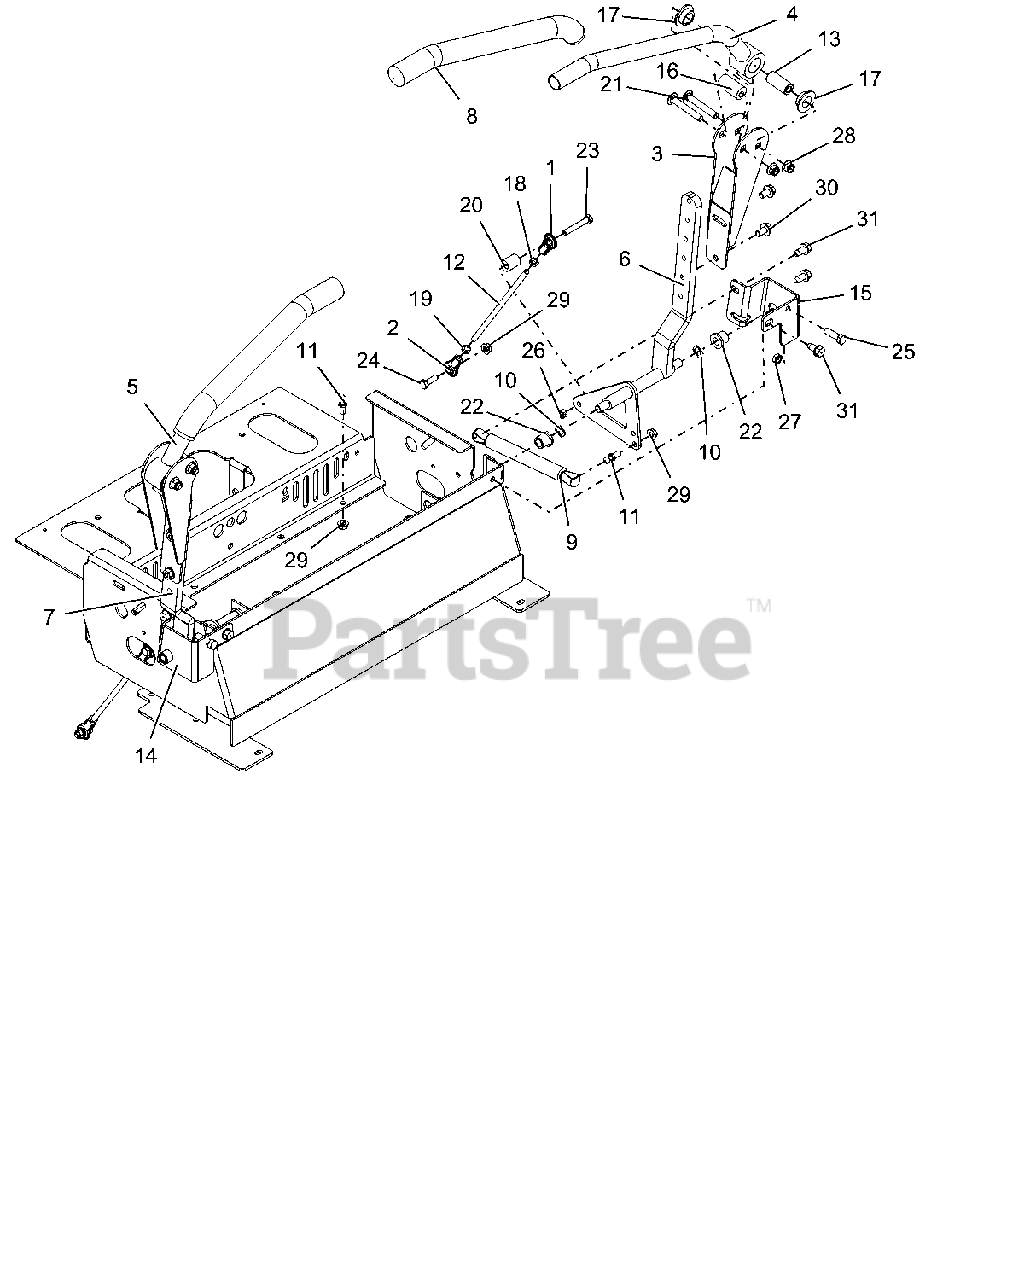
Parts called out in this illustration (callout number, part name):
1	ALIGNABALL, 5/16 RH THREAD
2	ALIGNABALL, 5/16 LH THREAD
3	WLDMT, UPPER ADJUSTABLE CONTROL ARM (BLACK)
4	WLDMT, LH CONTROL HANDLE
5	WLDMT, RH CONTROL HANDLE
6	WLDMT, LOWER LH CONTROL ARM
7	WLDMT, LOWER RH CONTROL ARM
8	GRIP, HANDLEBAR
9	DAMPER,
10	WAVE WASHER .531X.781X.125 FH
11	STUD-BALL
12	ROD, STEERING
13	SPCR, STEERING ARM
14	BRKT, PT200/400 RH CONTROL STOP (RED)
15	BRKT, PT200/400 LH CONTROL STOP (RED)
16	BSHG, ECCENTRIC .328 X .750 X 1.625
17	BSHG, FLANGE .762 X 1.48 X .44 NYLON
18	NUT-JAM
19	NUT, JAM -LH .31-24 YWZC
20	ECCENTRIC
21	BLT-RHDSSQNK .38-16X2.50 G5YZ
22	BHSG-FLG .500X.750X.750X.125
23	BLT-HEX .31-18X2.00 GR5 YWZC
24	BLT-HEX .31-18X1.00 GR5 YWZC
25	BLT-HEX .38-16X1.25 GR5 YWZC
26	NUT-LK-CTR .31-18 YWZC
27	NUT, JAM .375-16 YWZC
28	NUT-LK-NYL-FLG .38-16 YWZC
29	NUT, LK-TOP-FLG .312-18 YWZC
30	BLT-SERHFWH .38-16X.62 YWZC
31	SCR-TAP .38-16X.75 HWH TR YWZ
